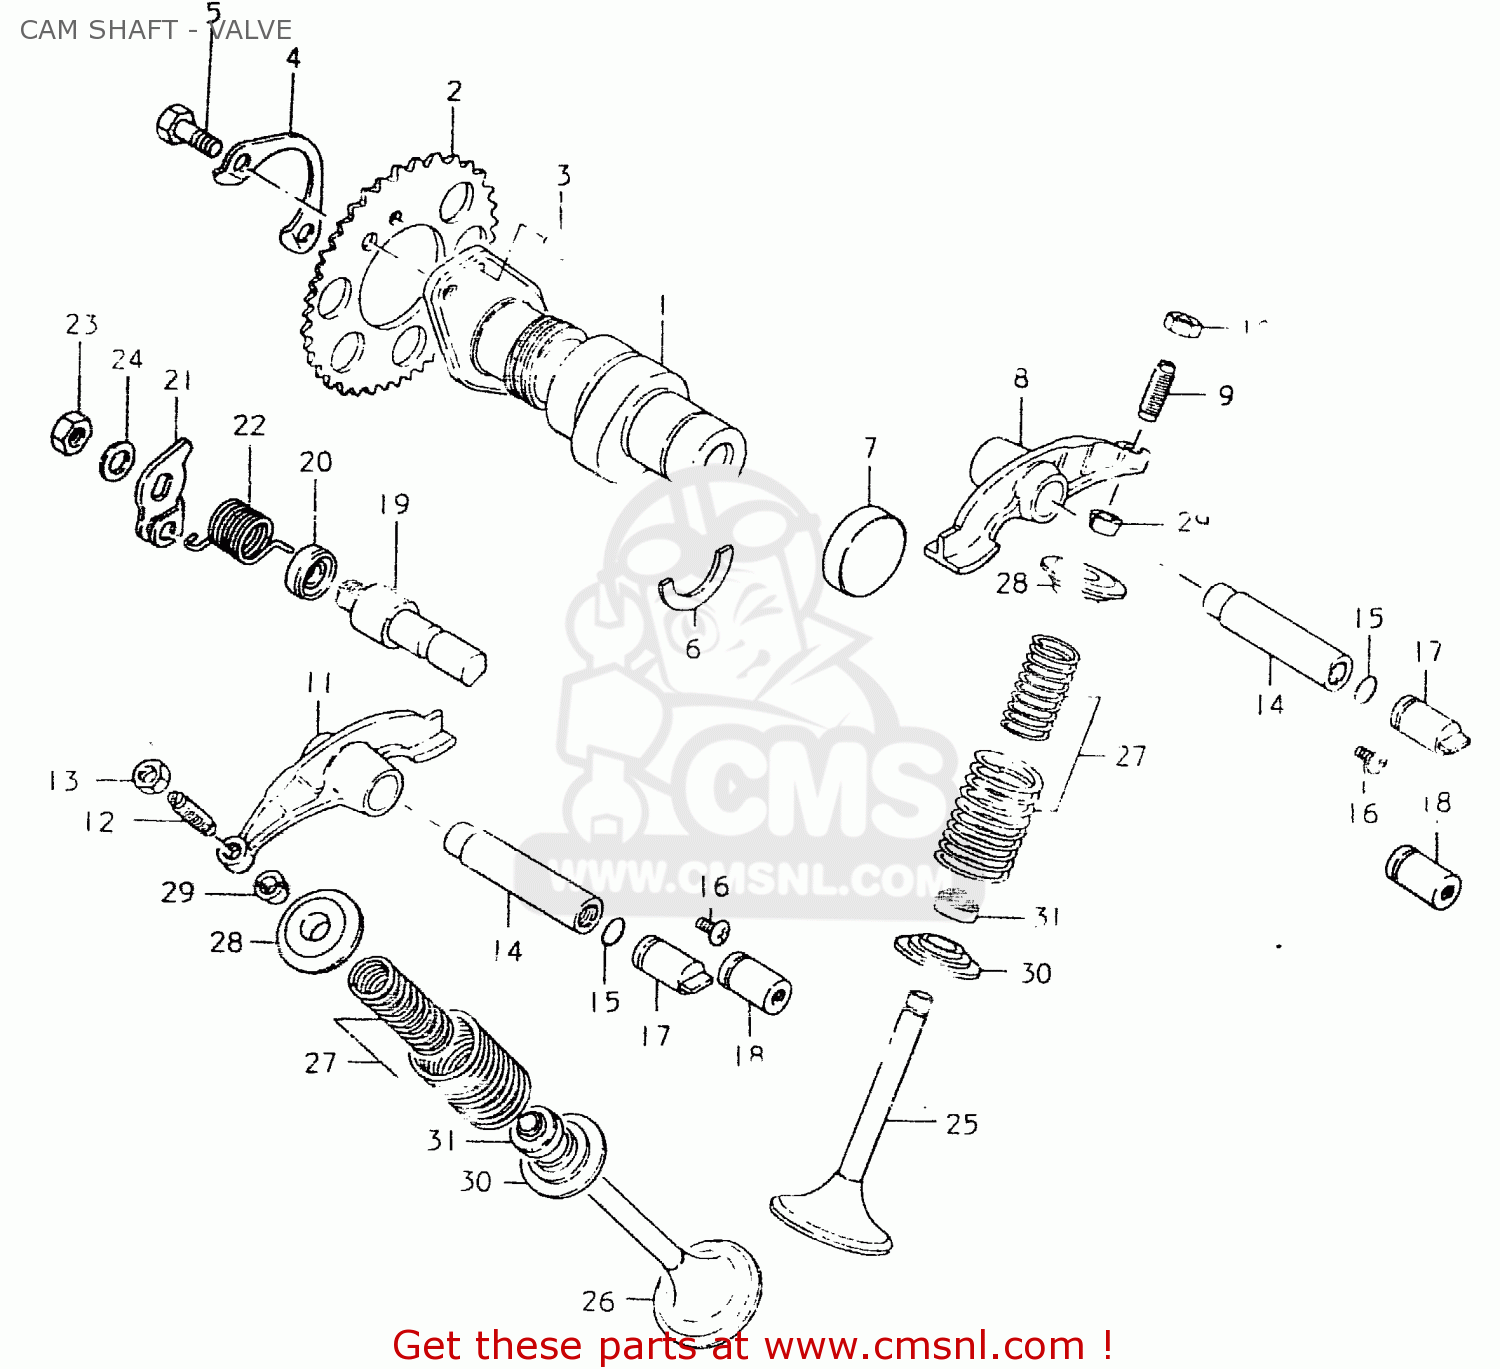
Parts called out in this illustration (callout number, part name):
1	CAMSHAFT
2	SPROCKET,CAMSHAFT
3	PIN
4	WASHER,CAM CHAIN SPROCKET
5	BOLT(6X12.5)
6	C RING
7	PLUG
8	ARM,VALVE ROCKER
9	SCREW,TAPPET ADJUSTING
10	NUT,ADJUSTING SCREW
11	ARM,VALVE ROCKER
12	SCREW,TAPPET ADJUSTING
13	NUT,ADJUSTING SCREW
14	SHAFT,VALVE ROCKER
15	O-RING
16	SCREW
17	CAP,ROCKER ARM SHAFT
18	CAP,ROCKER ARM SHAFT
19	SHAFT,DECOMPRESSION
20	OIL SEAL
21	LEVER,DECOMPRESSION SHAFT
22	SPRING
23	NUT 8MM
24	WASHER
25	VALVE,INTAKE
26	VALVE,EXHAUST
27	SHIM,TAPPET
28	RETAINER,VALVE SPRING
29	COTTER VALVE
30	SEAT,VALVE SPRING
31	SEAL,OIL(7X14.4X9)
